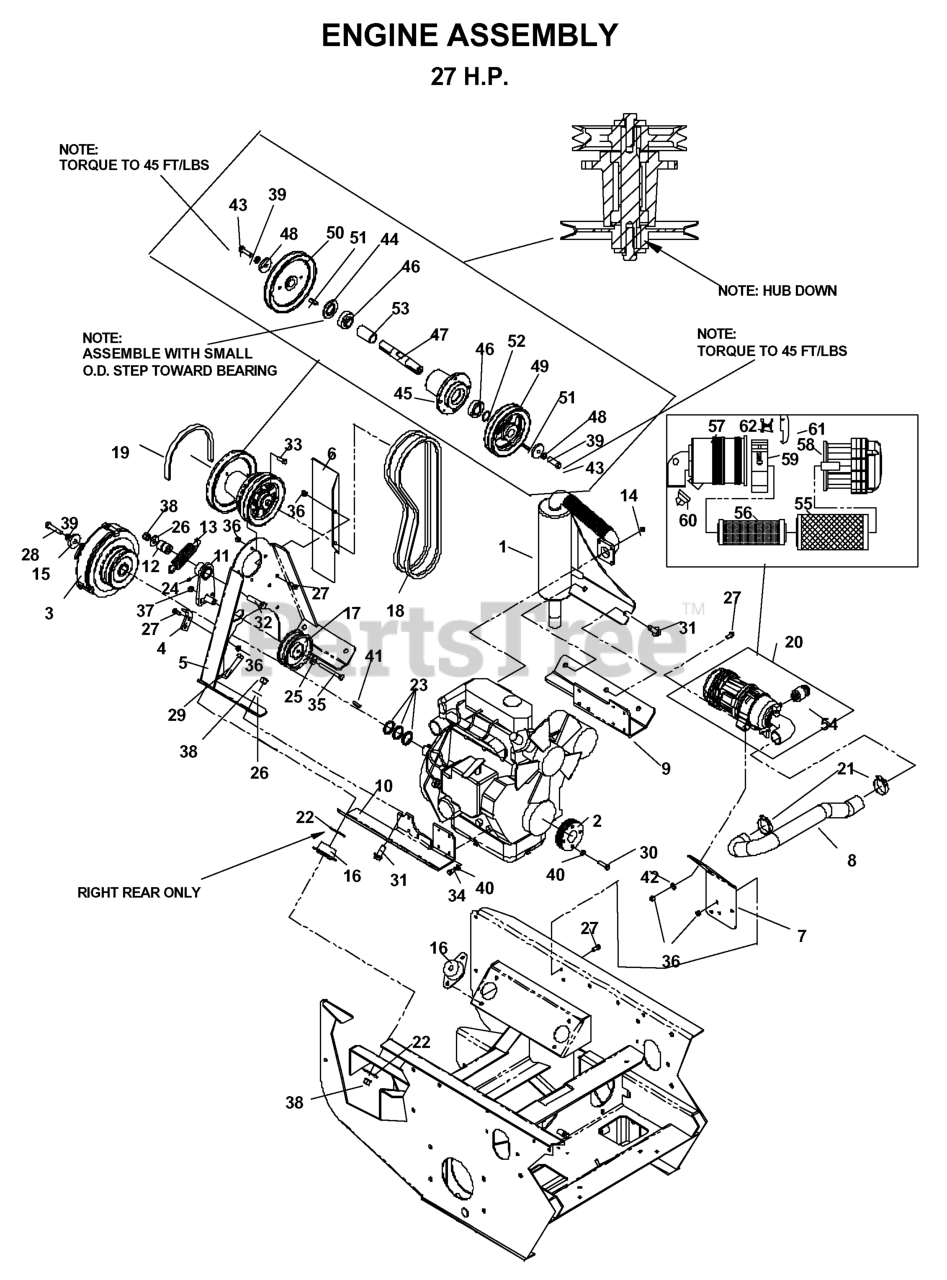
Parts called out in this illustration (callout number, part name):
2	ENGINE SHEAVE
3	CLUTCH
4	RESTRAINT
5	JACKSHAFT MOUNT WELDMENT
6	HEAT SHIELD
7	MOUNTING BRACKET
8	AIR FILTER HOSE
9	ENGINE MOUNT-LT
10	ENGINE MOUNT-RT
11	ARM WELDMENT
14	NUT M8-1.25 STOVER
15	SPINDLE WASHER
17	IDLER, PRIMARY
18	ENGINE BELT, PRIMARY
19	ENGINE, BELT MULE
20	AIR FILTER ASSY - NON-TURBO
22	ISOLATOR WASHER
23	BUSH 1-1/8 X 10 GA ZD
24	ZERK
25	WASHER 3/8 SAE FLAT
26	WASHER 1/2 FLAT
27	HCS 5/16C X 3/4
28	BOLT 7/16F X 2 1/2
29	HCS 1/2C X 2 3/4
30	HTB M8-1.125 X 25MM
31	HCS 1/2C X 1 1/4 SERRATED HEAD
32	HEX SCREW 1/2-13 X 2.5" GR 5
33	HCS 5/16C X 1
35	HCS 3/8-16 X 3-1/2 GR5 ZD
36	NUT 5/16 NYLOC
37	NUT 3/8-16 NYLOC
38	NUT 1/2-13 HEX NYLOC ZD
39	WASHER 7/16 LOCK
40	WASHER.LOCK.HVY.HLCL.SPR.5/16
41	KEY 1/4" SQ X 1 7/8"
42	WASHER 5/16 FLAT
43	HCS 7/16F X 1 1/2
44	COMBO SPACER
45	HOUSING, DIE CAST
46	BEARING
48	SPINDLE WASHER
51	KEY 1/4 SQ X 1 1/8
52	BUSHING.MACHINE.18.GAUGE
55	AIR FILTER
56	SAFETY ELEMENT
57	BODY - 90 DEG
58	PRECLEANER ASM
59	MOUNTING BRACKET
539106327	STUB SHAFT
539109177	MANIFOLD GASKET
